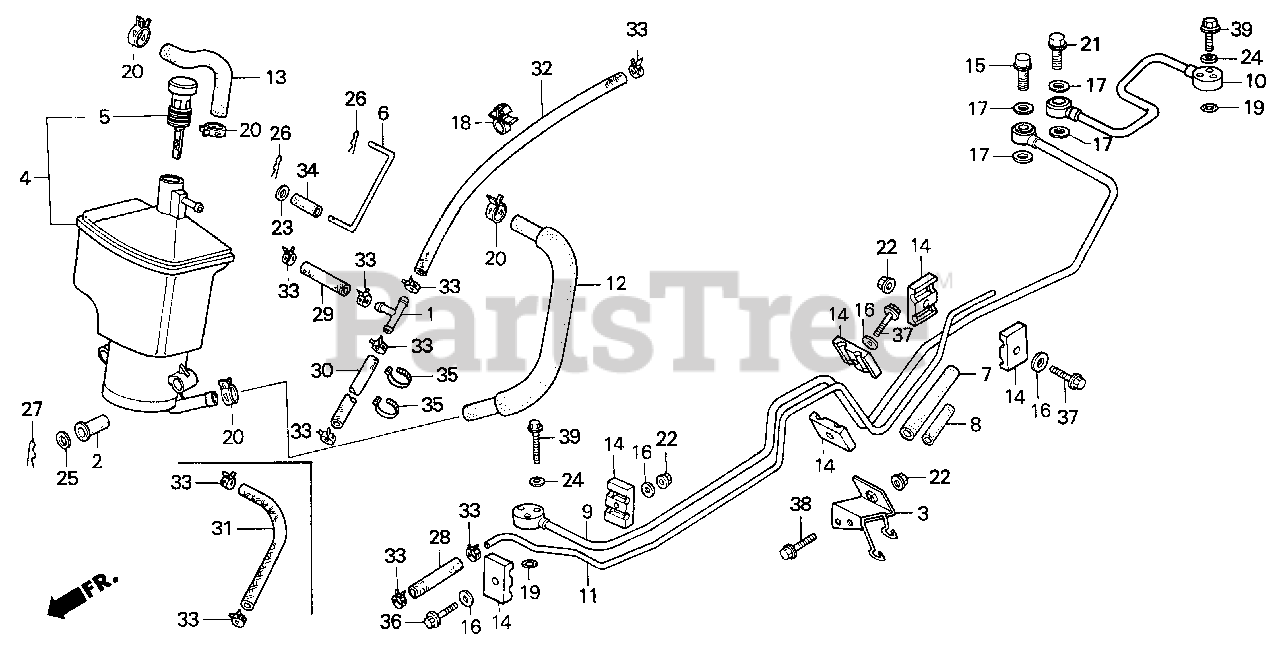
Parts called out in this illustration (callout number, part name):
2	CUSHION, FUEL TANK PIVOT
3	CLIP, DRAIN TUBE
4	TANK ASSY., OIL
5	CAP, OIL TANK
6	BRACKET A, OIL TANK
7	TUBE (12X200)
8	TUBE (8X100)
9	PIPE A, FEEDER
11	PIPE A, BREATHER
12	TUBE ASSY., SUCTION
13	TUBE, RETURN
14	SADDLE, PIPING
15	BOLT A, JOINT
16	WASHER (6.5X25X1.5)
17	WASHER, JOINT (14MM)
19	O-RING (11.8X1.9)
20	CLAMP D (19MM)
21	BOLT, DRAIN PLUG (14MM)
22	NUT, FLANGE (6MM)
23	WASHER, PLAIN (5MM)
24	WASHER, PLAIN (6MM)
25	WASHER, PLAIN (8MM)
26	PIN, LOCK (5MM)
27	PIN, LOCK (8MM)
28	BULK HOSE, FUEL (7.5X3000) (7.3X60)
31	BULK HOSE, FUEL (7.5X3000) (7.5X380)
33	CLAMP, TUBE (D12.5)
34	BULK HOSE, VACUUM (5X3000) (5X22)
35	BAND B1, WIRE
36	BOLT, FLANGE (6X28)
37	BOLT, FLANGE (6X32)
38	BOLT, FLANGE (6X16)
39	BOLT, FLANGE (6X35)
